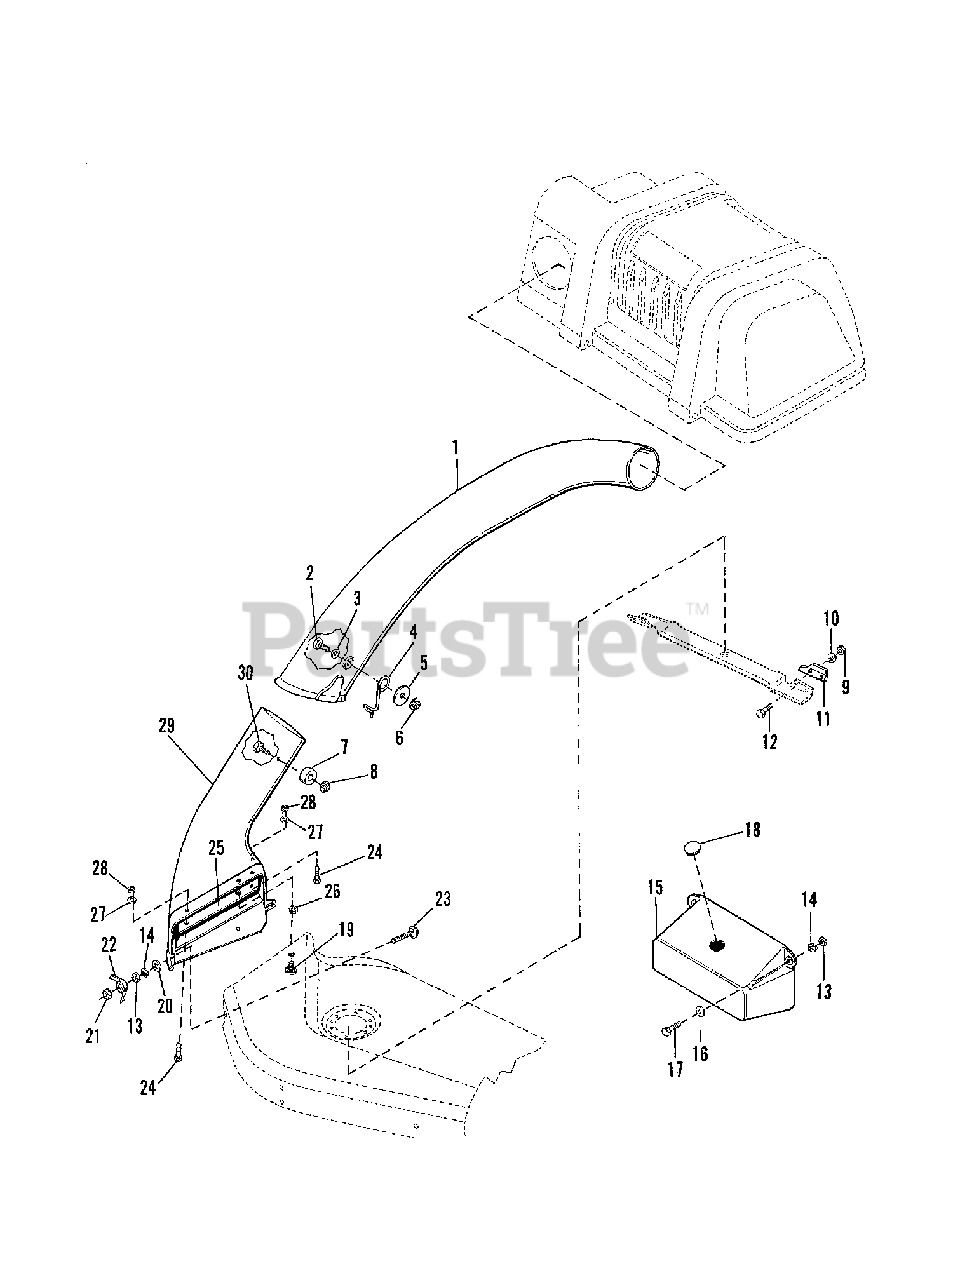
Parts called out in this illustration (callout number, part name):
1	TRANSFER TUBE
2	CAPSCREW, Hex Head, 5/16-18 x 3/4
3	WASHER, Flat, 5/16
4	LATCH, Tube
6	NUT, Flange Lock, 5/16-18
7	WASHER, Flat
8	NUT, Esna, Hex Lock, 5/16-18
9	NUT, Hex, 1/4-20
10	LOCKWASHER, 1/4
12	CAPSCREW, Hex Head, 1/4-20 x 5/8, Gr. 8
13	NUT, Hex Head,Flange, 5/16-18
14	LOCKWASHER, 5/16
15	COUNTERWEIGHT
16	WASHER
17	CAPSCREW, Hex Head, 5/16-18 x 1
19	CARRIAGE BOLT, 5/16-18 x 1-1/4
21	NUT, Hex, Toplock, 5/16-18
22	WING NUT ASSEMBLY, 5/16-18
23	CARRIAGE BOLT, 5/16-18 x 2
24	SCREW, Flat Head, #10-24 x 5/8
25	STRAP, Reinforcement
26	NUT, Hex, Jam, 5/16-18
27	WASHER, Flat
28	NUT, Hex Head, #10-24
30	CAPSCREW, Hex Head, 5/16-18 x 3/4
